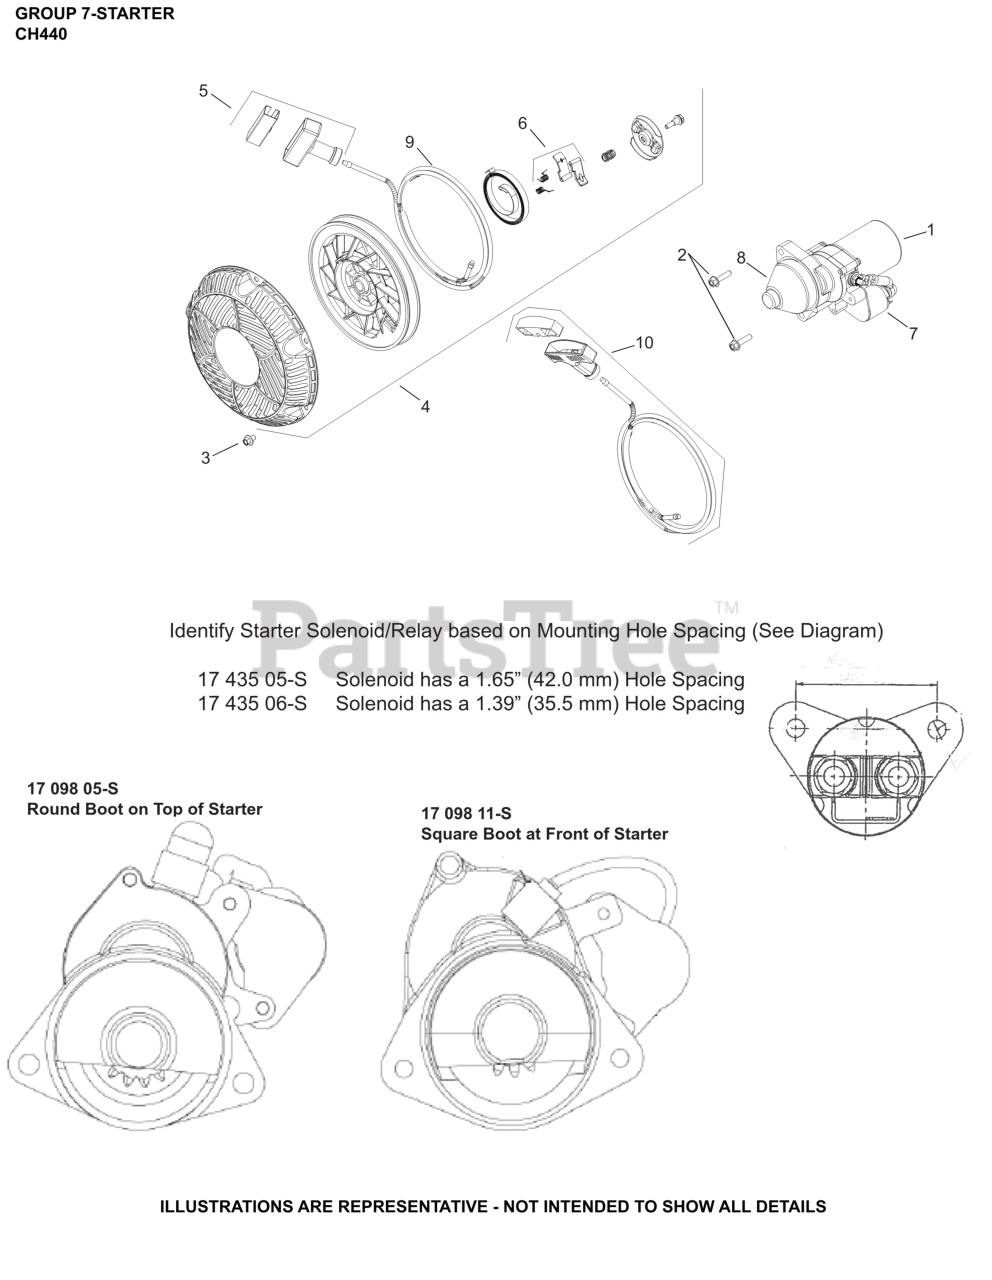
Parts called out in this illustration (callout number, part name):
1	ELCTRC START,BENDIX DRV W/SOLENOID
3	SCREW, M6 X 8 HEX FLANGE HEAD
4	RETRACTABLE STARTER ASSY-(#1716522S)
5	KIT, HANDLE
6	KIT, PAWL REPAIR
8	KIT, STARTER DRIVE
